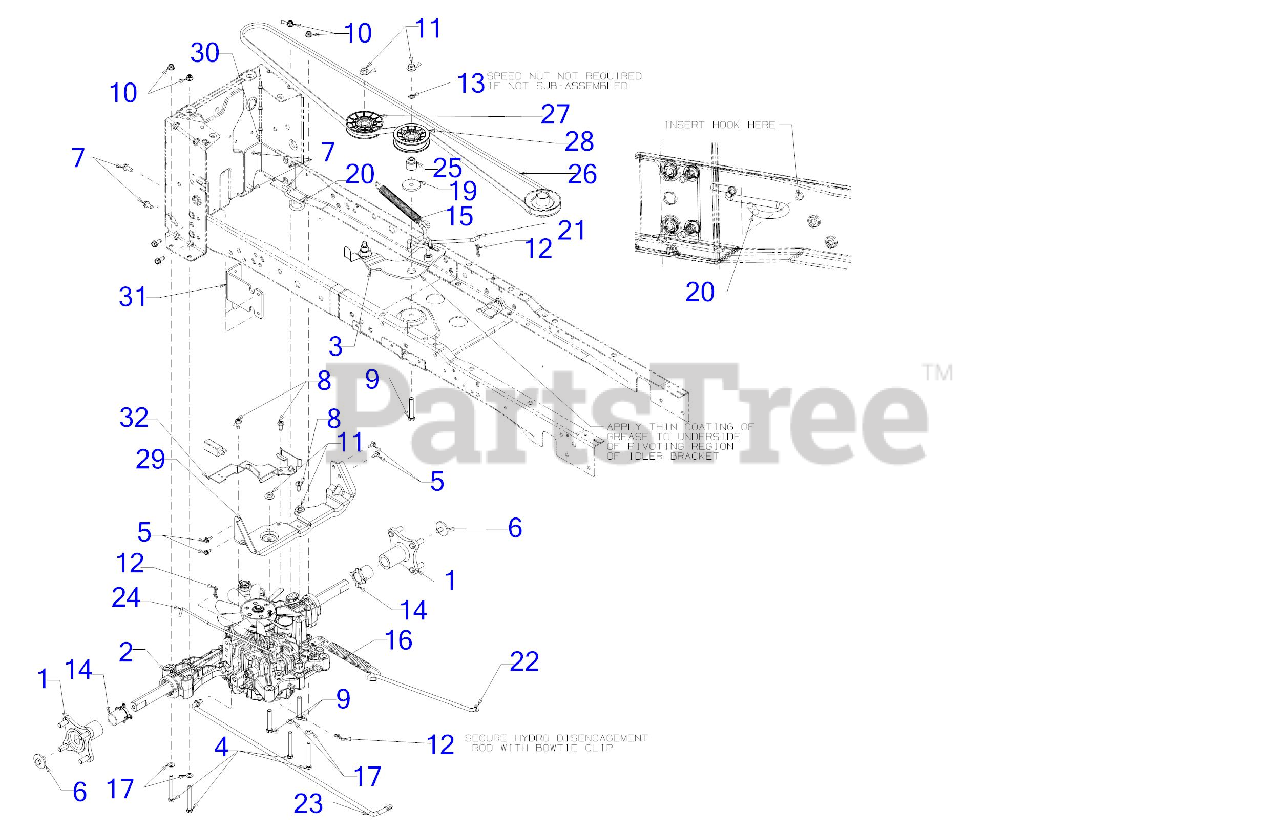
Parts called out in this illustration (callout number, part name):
1	WHEEL HUB ASSEMBLY
2	TRANSMISSION ASSEMBLY
3	IDLER BRACKET ASSEMBLY
4	HEX SCREW 5/16-18 x 2.75
5	SCREW M6-1 x .625
6	SCREW 3/8-16 x .75 GR5.1
7	SCREW 5/16-18 x .750
8	SCREW M8-1.25 X .750
9	SCREW 3/8-16 x 2.25 GR5
10	FLANGE LOCK NUT 5/16-18
11	FLANGE LOCK NUT
12	BOW TIE COTTER PIN 1/4-5/16
14	AXLE SLEEVE 1.02 ID x 1.60 LG
15	EXTENSION SPRING .790 DIA x 8.41
16	EXTENSION SPRING 0.90 DIA x 8.14
17	FLAT WASHER
19	SHOULDER SPACER
20	DECK SPRING HOOK
21	IDLER BRACKET ROD
22	BRAKE ROD
23	HYDRO CONTROL ROD
24	HYDRO DISENGAGEMENT ROD
25	SHOULDER SPACER
26	V-BELT A SEC x 91.10
27	V-IDLER PULLEY 3.56 OD
28	FLAT IDLER PULLEY 3.00 OD
29	TRANSMISSON MOUNTING BRACKET
